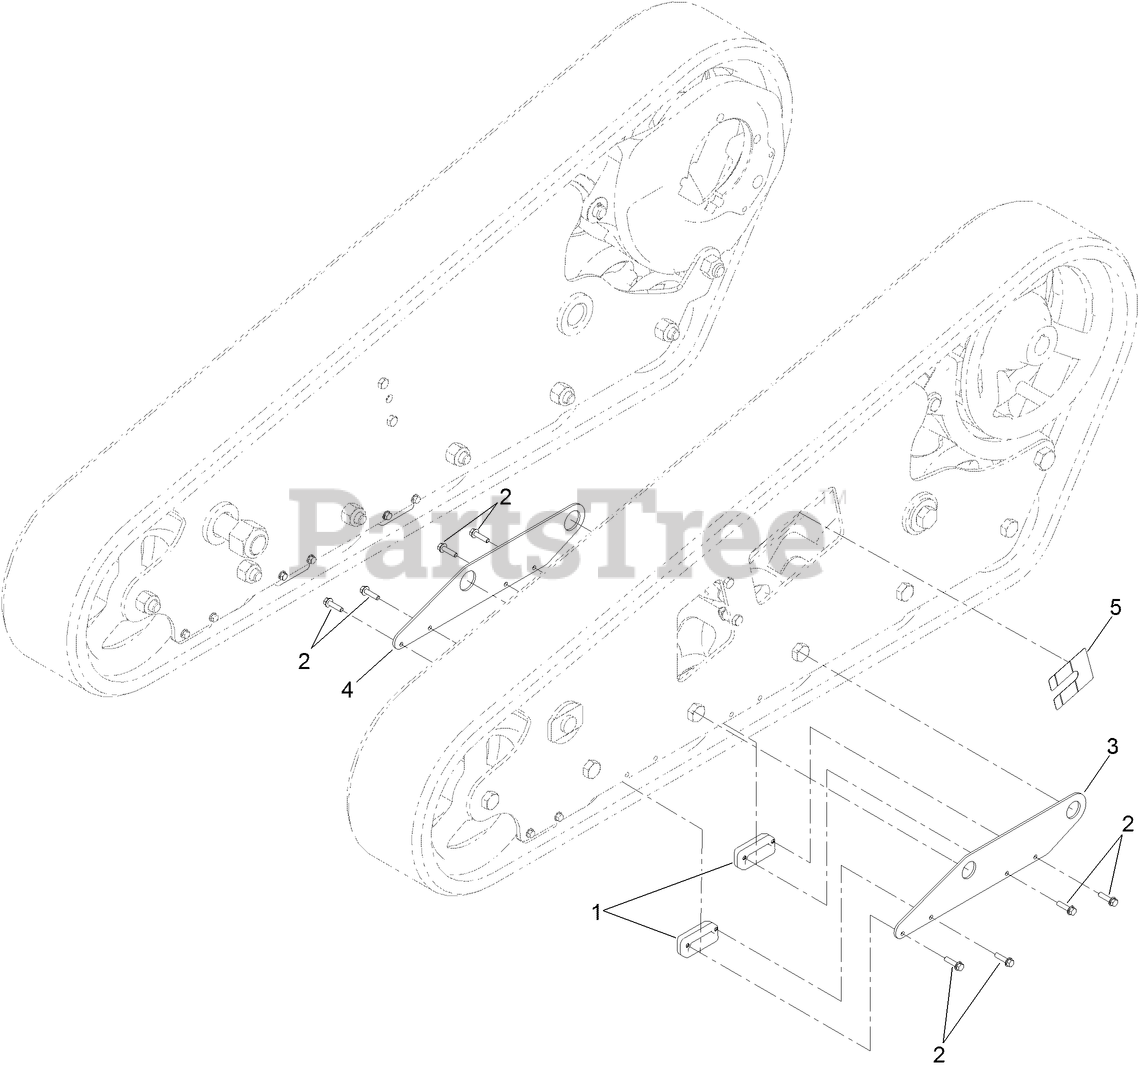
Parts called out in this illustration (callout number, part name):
1	BLOCK-TRACK
2	SCREW-HHF
3	TEMPLATE-TRACK, OUTSIDE
4	TEMPLATE-INSIDE, TRACK
5	DECAL-INDICATOR, TENSIONER
